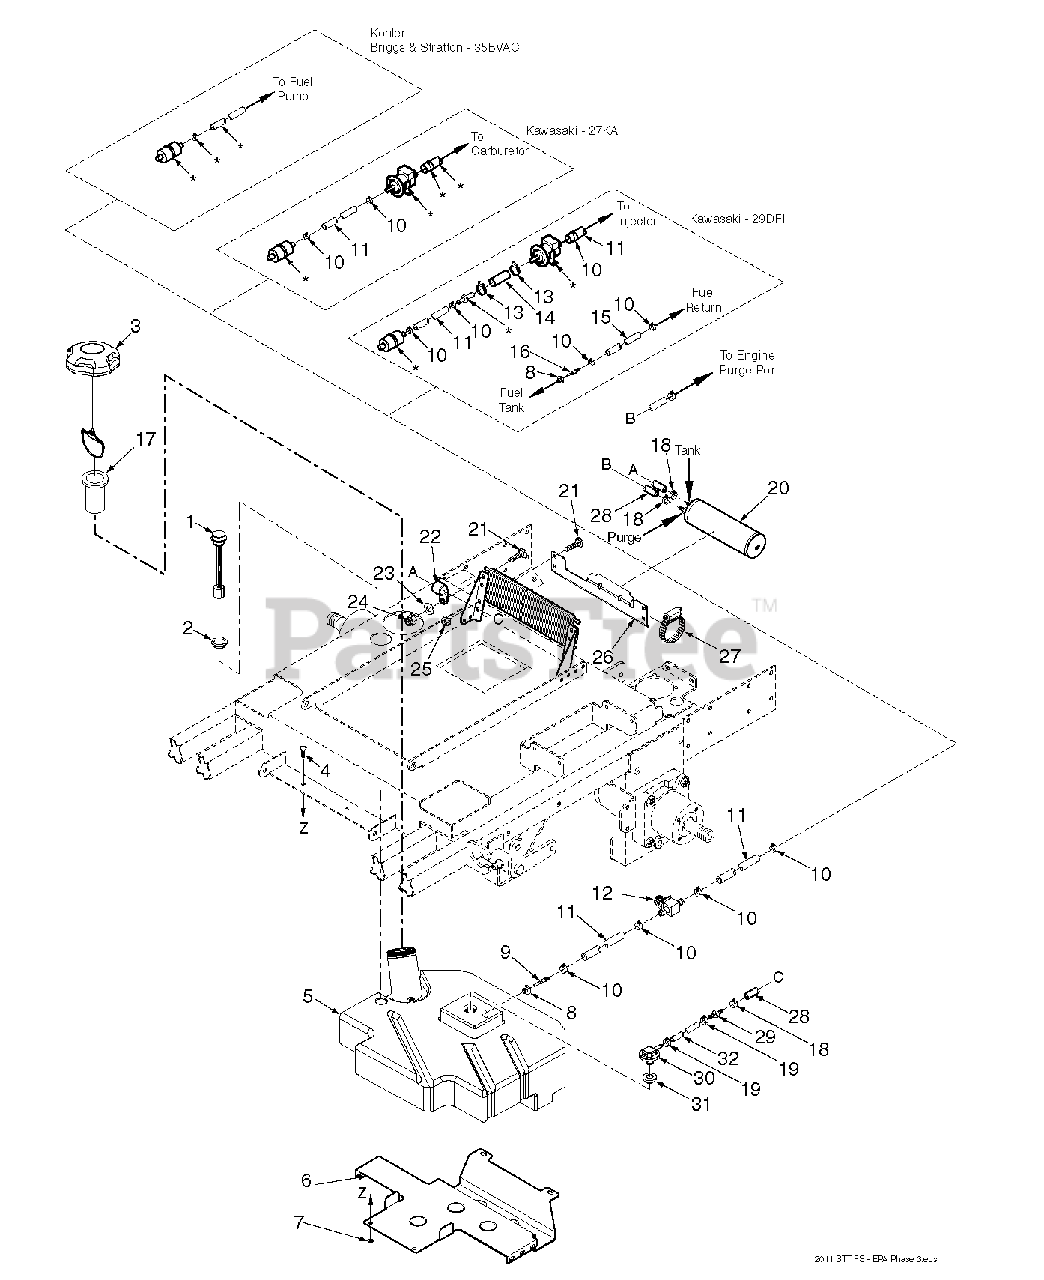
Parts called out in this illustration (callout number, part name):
1	Fuel Gauge Assembly
2	Seal, Fuel Gauge
3	Fuel Cap, Tethered
4	Bolt, Carriage 1/4-20 x 3/4"
5	Fuel Tank Assembly - STT
5	Fuel Tank Assembly - STT-DFI / EFI
6	Support Bracket, Fuel Tank
7	Nut, 1/4-20 Serrated Flange
8	Bushing, .56 Dia. Viton
9	Hose Fitting
10	Clamp, Fuel Hose 5/16" I.D.
11	Fuel Hose, 5/16" I.D. Non-Perm
12	Valve, Fuel Shut-Off
13	Clamp, .87" Max. Dia
14	Fuel Hose, 1/2" I.D. Non-Perm
15	Fuel Hose, 1/4" I.D. Non-Perm
16	Return Fitting, Straight
17	Tube, Fuel Tank Insert - 6"
18	Clamp, Vapor Recovery Hose 3/16"
19	Clamp, Fuel Hose 7/32 ID
20	Carbon Canister
21	Bolt, Carriage 1/4-20 x 3/4"
23	Flatwasher, 1/4-.281 x .562 x .049
24	Nut, 1/4-20 Elastic Stop
25	Nut, 1/4-20 Serrated Flange
26	Bracket, RH Canister Mounting
28	Hose, 3/16
29	Mender, 1/4 x 3/16 w/.02 Hole
30	Valve, Rollover
31	Grommet, Viton
32	Hose, 1/4" Vapor Recovery
